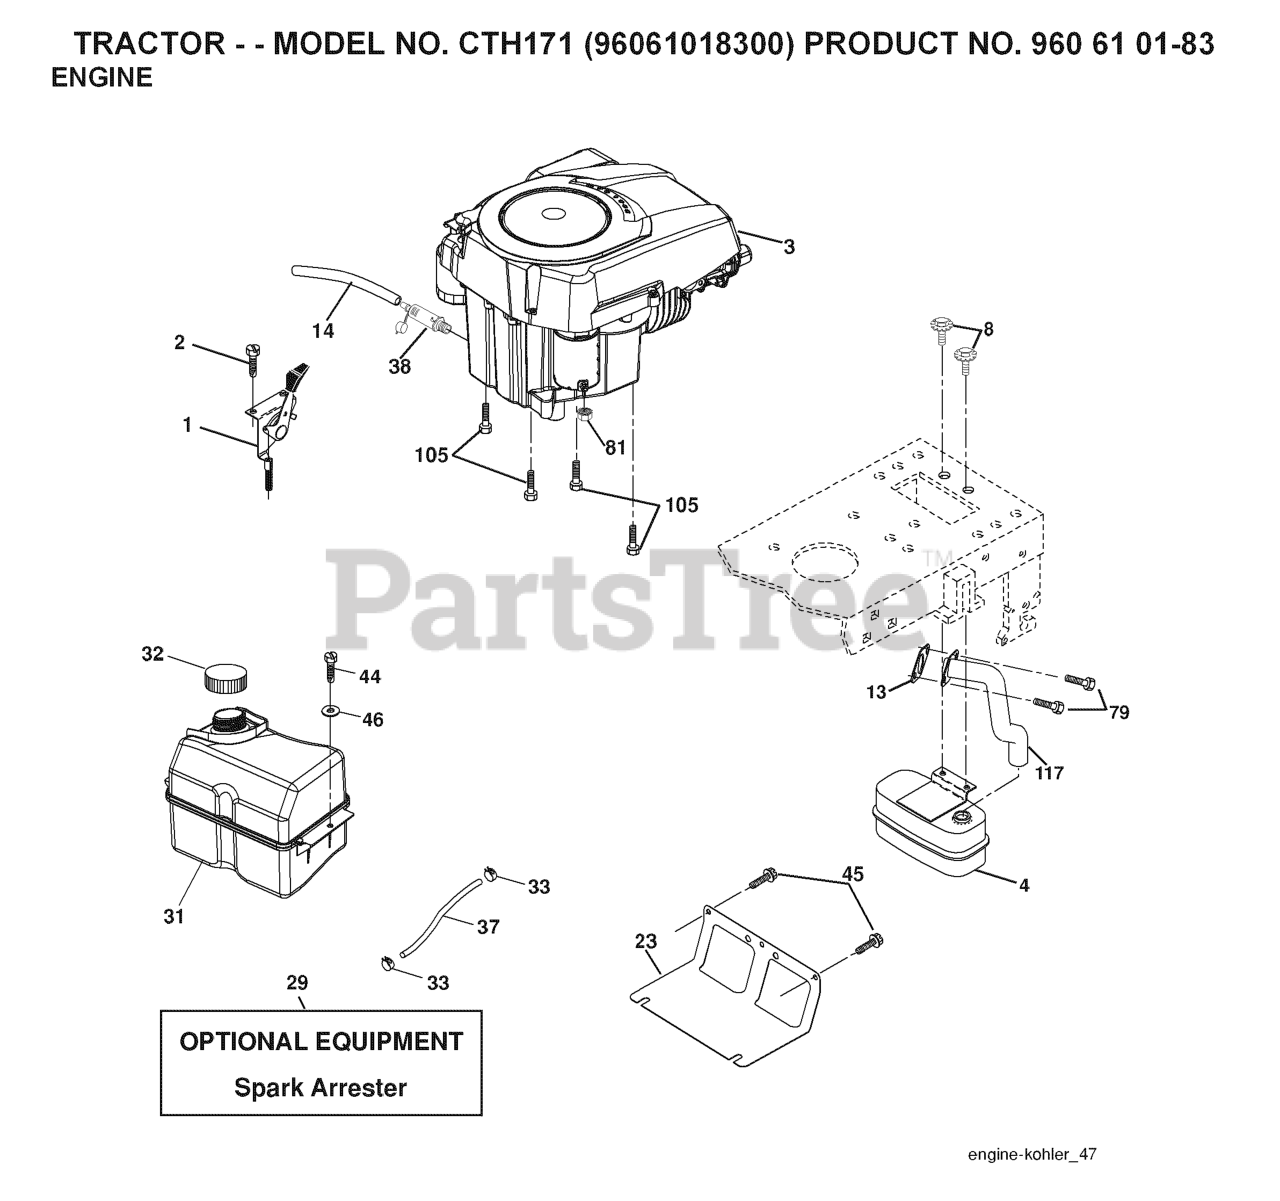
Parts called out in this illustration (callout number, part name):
1	CONTROL.TH/CK.C.
2	SCREW
4	MUFFLER.SINGLE.CYL.KOHL/B&S
8	BOLT.5/16-18UNCX3/4 W/SEMS.BLK
13	GASKET.EXHAUST.KOHLER
14	TUBE, DRAIN OIL ASM.
23	SHIELD.BROWNING.DBR.GUARD
29	KIT.SPARK ARRESTOR 794945 B&S
31	RP TANK FUEL FRT 1.5 GAL
32	FUEL CAP
33	HOSE CLAMP
37	LINE.FUEL.20
38	PLUG DRAIN OIL EASY
44	SCREW HEXWSHR 1/4-20X3/4
45	SCREW, 3/8-16X3/4
79	SCREW.SOCKET HD.5/16-1
81	NUT
105	SCREW 3/8-16X1
117	RP.TUBE.EXHAUST.KOHL.COURAGE
